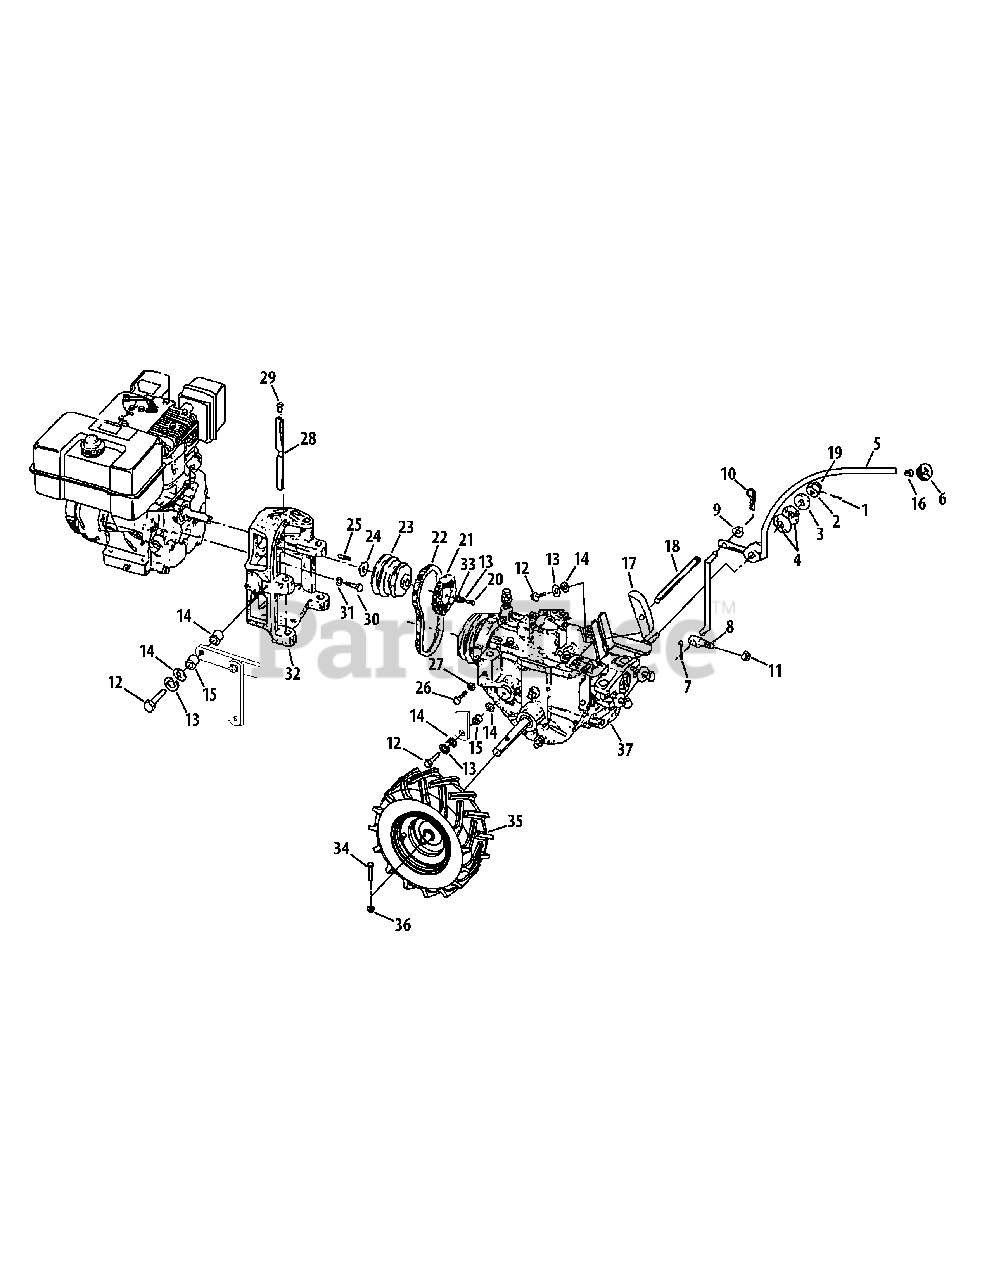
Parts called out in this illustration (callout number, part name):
1	Spring Pin, 1/8"
2	Flat Washer, .510 x 1.0 x .125
3	Shoulder Washer, 1.25 x .50 x .25
4	Disc Spring Washer
5	Wheel Speed Shift Lever
7	Cotter Pin, 3/32" x 1"
9	Flat Washer, .344 x .688 x .065
10	Hair Pin Cotter
11	Hex Locknut, 5/16"-18
12	Hex Head Screw, 3/8-16 x 1"
13	Lockwasher, 3/8"
14	Flat Washer, .406 x .810 x .051
15	Bushing Spacer, .5 x .375 x .3
16	Retaining Ring
17	Belt Adjustment, 3-7/8"
18	Belt Adjustment Rod
19	Hex Nut, 1/2-20
20	Hex Head Screw, 3/8-24 x 1.75
21	Reverse Disc
22	Forward Drive Belt
23	Engine Power Take-off Pulley
24	Flat Washer, .766 x 1.0 x .031
24	Flat Washer, .766 x 1.0 x .062
25	Engine Pulley Key, 3/16"x 2-1/2"
26	Hex Head Screw, 5/16-18 x 1"
27	Hex Nut, 5/16-18
28	Engine Mounting Bar
29	Thread Protector Plug
30	Hex Head Screw, 5/16-24 x 1.125
31	Lockwasher, 5/16"
33	Flat Washer, .406 x 1.0 x .105
34	Hex Screw, 1/4-20 x 1-1/2
35	Wheel Assembly, 16 x 4.6 x 8"
35	Tire, 16.2 x 4.6
36	Hex Flange Nut, 1/4-20
37	Clutch Bracket
